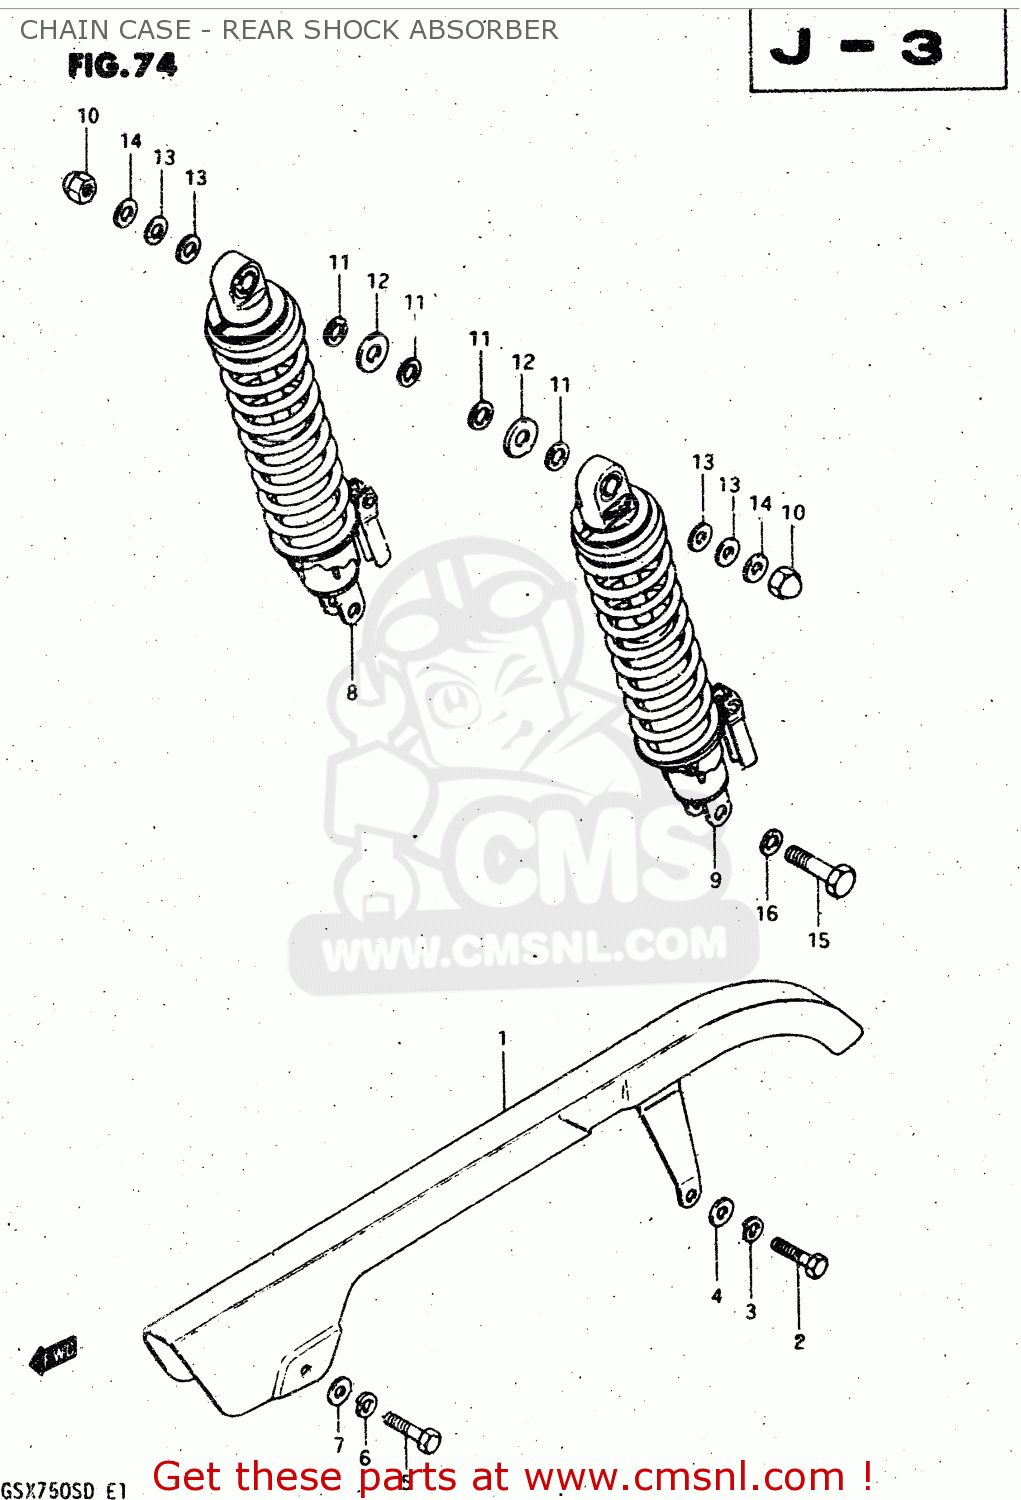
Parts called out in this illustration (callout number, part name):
1	CASE,CHAIN
2	BOLT
3	LOCK WASHER
4	WASHER
5	BOLT
6	LOCK WASHER
7	WASHER
8	SHOCK ABSORBER, REAR RH
9	SHOCK ABSORBER, REAR LH
10	NUT, LOWER LH
11	WASHER
12	WASHER (12.5X24X3.2)
13	WASHER
14	WASHER(10.5X24X3.2)
15	BOLT(10X36)
16	WASHER
